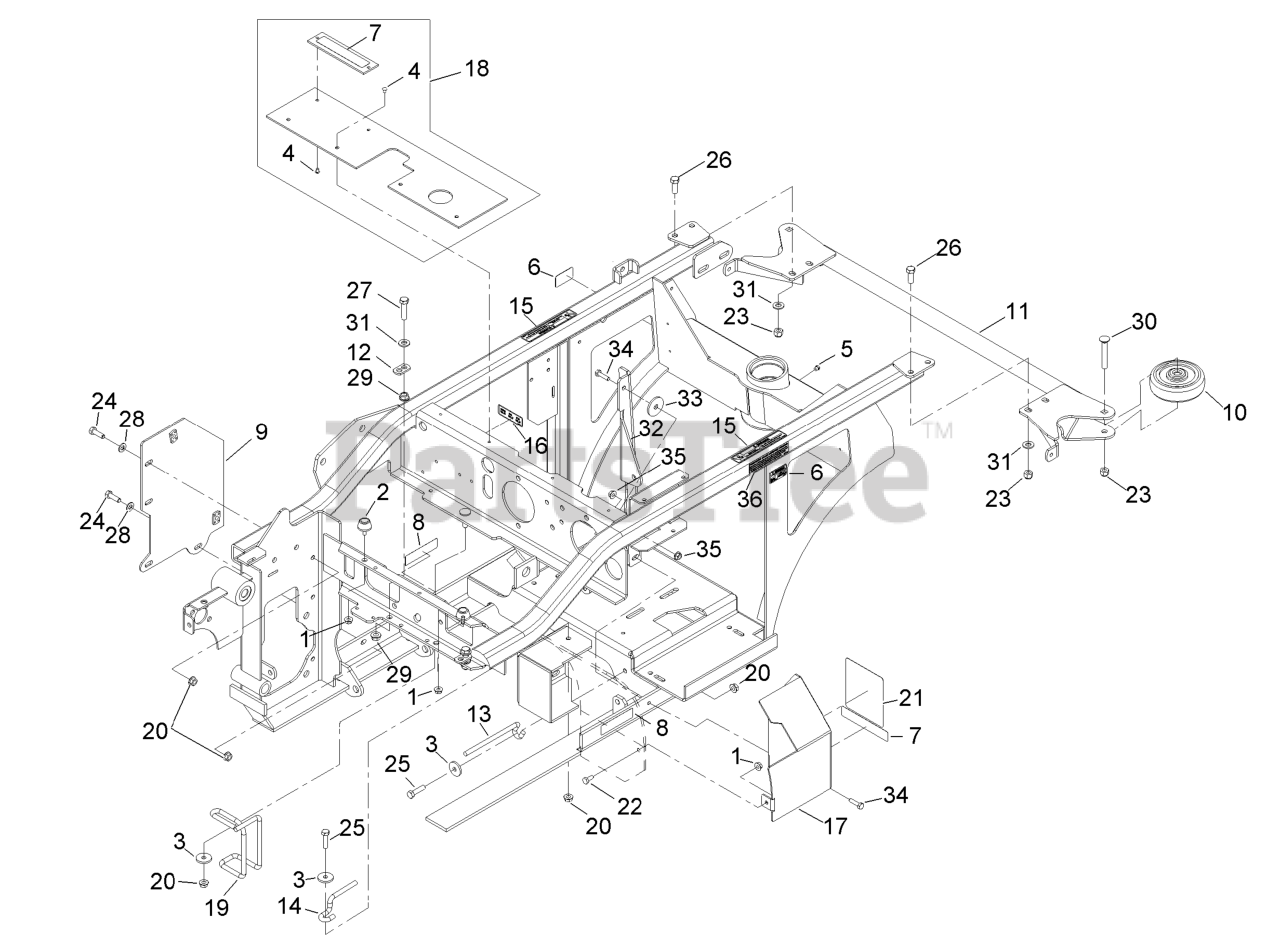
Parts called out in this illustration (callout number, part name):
2	BUMPER-RUBBER
4	RIVET-POP
6	DECAL-SURFACE, HOT
7	DECAL-WARNING
8	DECAL-COVER, MISSING
9	WLD,FENDER (RAW)
10	ROLLER-BUMPER
11	BUMPER-REAR
12	TAB,SPRING ANCHOR
13	GUIDE-BELT
14	GUIDE-BELT
15	DECAL,PINCH POINT
16	DECAL,RELAY
18	LIFT SHIELD ASM
19	GUIDE,BELT (PLATED)
21	DECAL,BELT ROUTING
22	SCREW-HH
23	NUT-LOCK, NI
24	SCREW-HH
25	SCREW-HH
26	SCREW-HH
27	SCREW-HH
28	WASHER-PLAIN
29	NUT-HHF, WHIZ
30	SCREW-CARR
31	WASHER-FLAT
32	BRACE-PTO
34	SCREW-HH
36	DECAL-ARRESTER, SPARK
